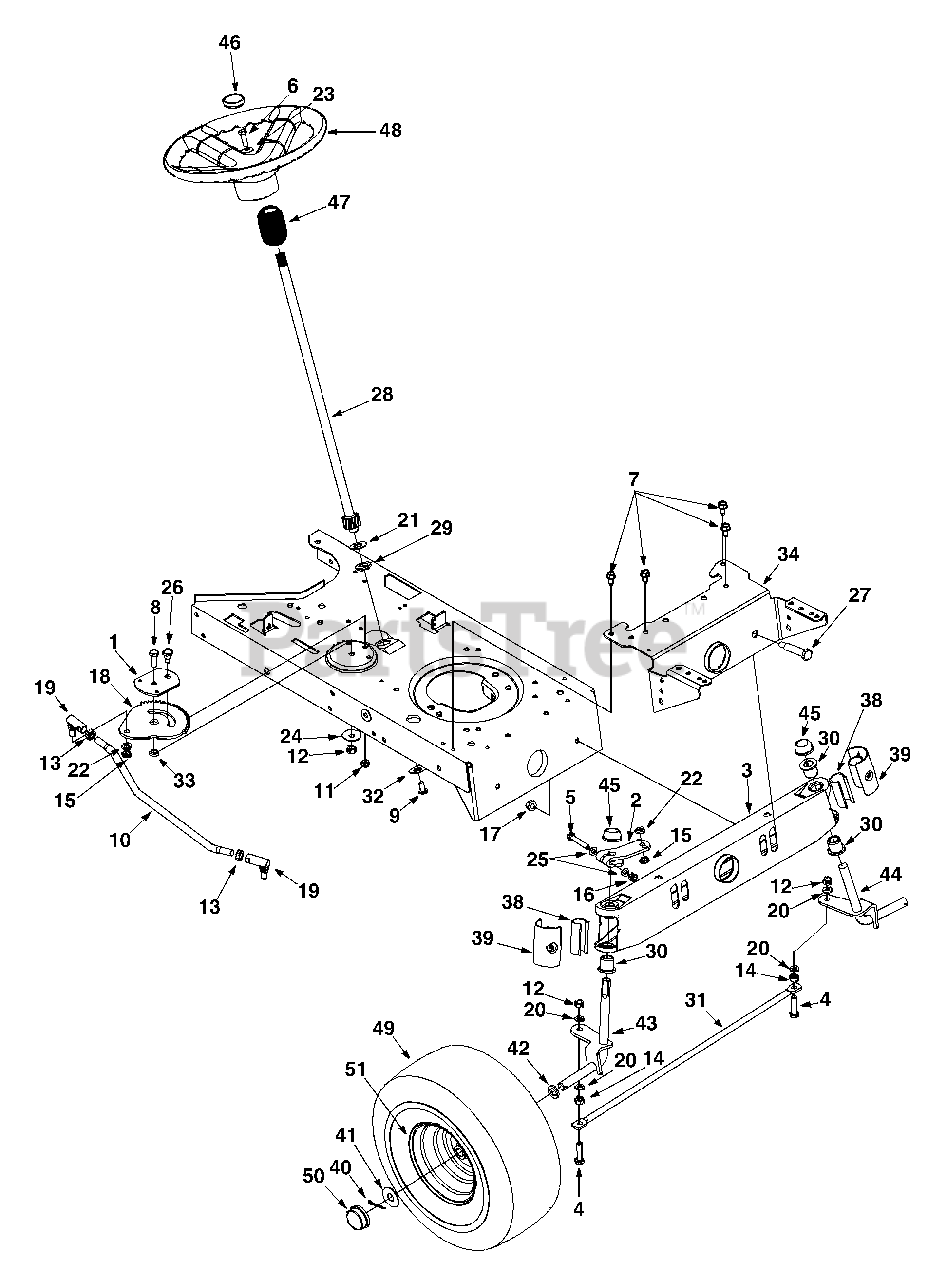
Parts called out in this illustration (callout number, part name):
1	Retainer Plate
2	Steering Arm Front Axle
4	Hex Bolt 3/8-24 x 1.5" Lg. (Gr. 5)
5	Hex Bolt 5/16-24 x 2.25" Lg.
6	Hex Bolt 5/16-18 x 1" Lg.
7	Hex Wash. Hd. Self-Tap Scr.
8	Hex Hd. Cap Scr. 3/8-24 x 1.0 Gr. 5
9	Hex Patch Bolt 5/16-18 x .62"
10	Steering Drag Link
11	Hex Cent. L-Nut 5/16-18 Thd.
12	Hex Cent. L-Nut 3/8-24 Thd.
13	Jam Nut 7/16-20 Gr. 2
14	Hex Nut 3/8-24 Gr.5
15	Hex Jam Nut 3/8-24 Thd.
16	Hex L-Nut 5/16-24 Thd.
17	Flanged L-Nut 3/8-16 Thd.
18	Steering Gear Segment
19	Ball Joint 7/16-20 Thd.
20	L-Wash. 3.8" I.D.
21	Fl-Wash. (Hardened)
23	Bell. Wash. .340 I.D. x .872 O.D.
24	Bell. Wash. .39 I.D. x 1.38 O.D.
25	Fl-Wash. .320 x .600 x 060
26	Shoulder Bolt .437 x .35 Lg.
27	Shoulder Bolt
28	Steering Shaft
29	Hex Flg. Brg. .634 I.D.
30	Hex Flg. Brg. .632 I.D.
32	Cap
33	Spacer .380" I.D. x .625" O.D.
39	Pivot Bar End Cap
41	Fl-Wash. .635 I.D. x 1.589 O.D.
42	Fl-Wash. .641 I.D. x 1.0 O.D.
43	Front Axle Assembly R.H.
44	Front Axle Assembly L.H.
46	Steering Wheel Cap
47	Steering Bellow
48	Steering Wheel
49	Wheel Assembly Comp.
50	Front Wheel Hub Cap
51	Front Wheel Rim Only
